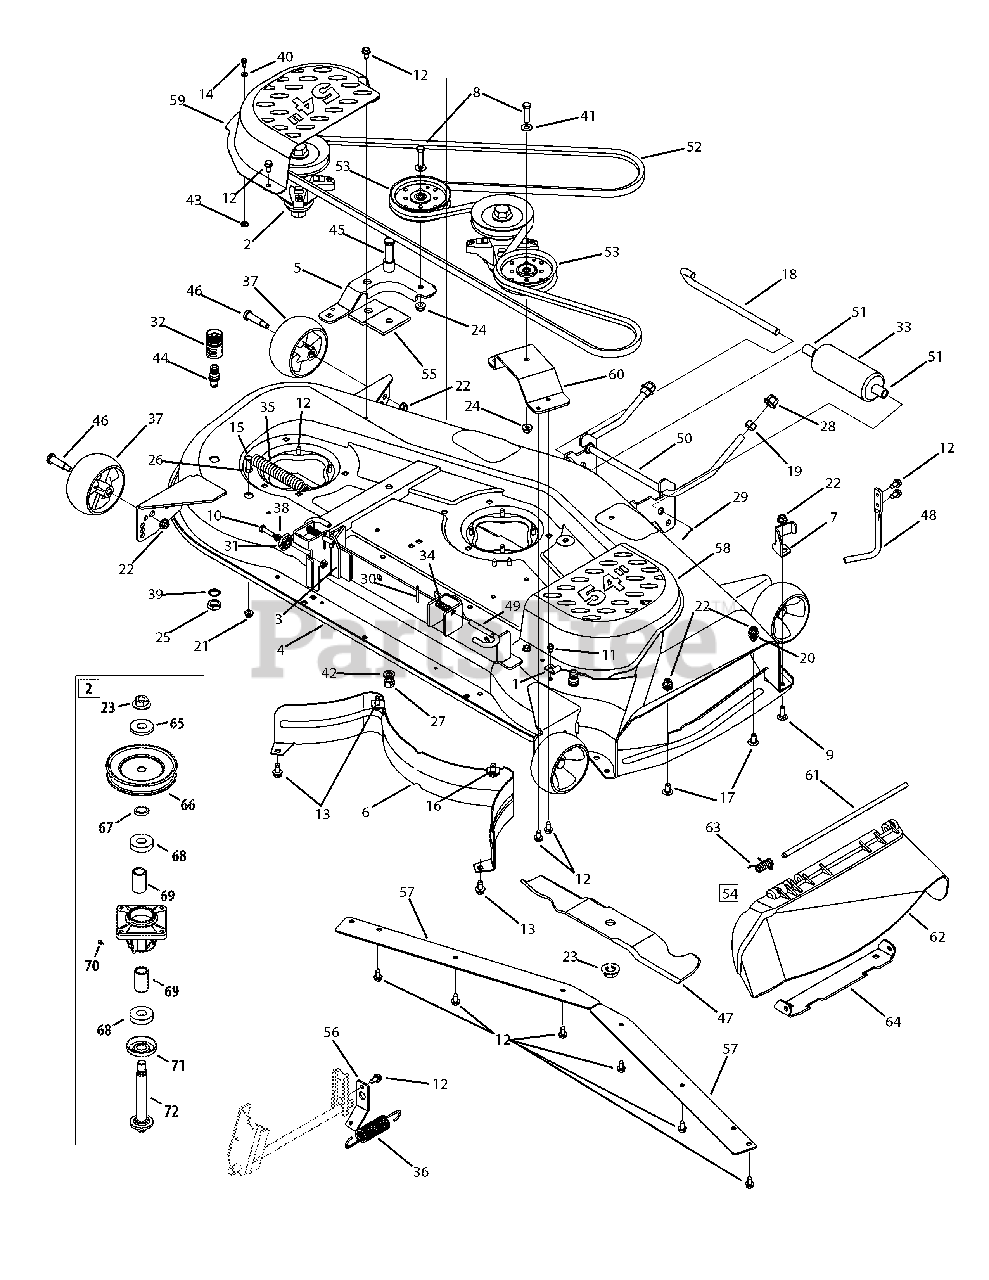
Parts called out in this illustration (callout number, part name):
1	Hook, Retainer Bracket
2	Spindle Assembly
8	Screw, 3/8-16 x 1.75
9	Screw, 3/8-16 x 1.0
10	Screw, 5/16-18 x 1.25
11	Screw, 1/4-20 x.500
12	Screw, 5/16-18 x .750
13	Screw, 3/8-16 x.750
14	Screw, 5/16-18 x .875
15	Screw, 5/16-18 x 2.00
16	Bolt, Carriage, 3/8-16 x 1.00
17	Bolt, Carriage, 3/8-16 x.750
18	Pin, Roller,.5" Dia. x 10.06
19	Nut, Hex, 1/2-13
20	Push Nut, 3/8
21	Nut, Flange Lock, 5/16-18
22	Nut, Flange Lock, 3/8-16
23	Nut, Hex, Flange, 5/8-18
24	Nut, Flange Lock, 3/8-16
25	Nut, Hex, M16-1.5
26	Nut, Hex, 5/16-18
27	Nut, Hex Lock, 1/2-13
28	Nut, Hex Lock, 1/2-13
29	Pin, Cotter, 3/32 x 1.00
30	Pin, Cotter, 1/8 x 1.25
31	Deck Adjustment Gear
32	Hose Coupler
33	Front Roller
34	Spring,.531OD x 1.75
35	Spring, Ext., .850 Dia. x 6.415
36	Spring, Ext., 1.010 Dia. x 6.50
37	Deck Wheel
38	Washer, Lock, 5/16
39	Washer, Lock, 5/8, Internal Tooth
40	Washer, Flat, .344 x .688 x .065
41	Washer, Flat,.406 x.875 x.059
42	Washer, Lock, 1/2
43	Washer, Flat,.407 x .812 x .135
44	Port, Water
45	Screw,.625 x 2.50 x 1/2-13
46	Shoulder Screw, .496 x 2.50, 3/8-16
47	Blade, 18.5"
48	Rod, Upstop, 54" LT
49	Rod, Deck Release Handle
50	Rod, Adjust. Front Deck .5" Dia.
51	Spacer,.550 ID x.755 OD x 1.1
52	V-Belt
53	Pulley, Idler, 4.25" Dia.
54	Discharge Chute Ass’y.
56	Lift Bracket, 54" Deck
62	Defltr. Chute
63	Torsion Spring
64	Chute Bracket
65	Washer, Flat, .760 x 1.5 x .120
66	Pulley, 5.39"
67	Spacer, .790 x 1.25 x .175
68	Ball Bearing, .787 x 1.85 x .551
69	Spacer, .800 x 1.10 x 1.322
70	Lube Fitting, 3/16
71	Spacer, .79 x 1.84 x .55
72	Shaft, Spindle, 5.75
